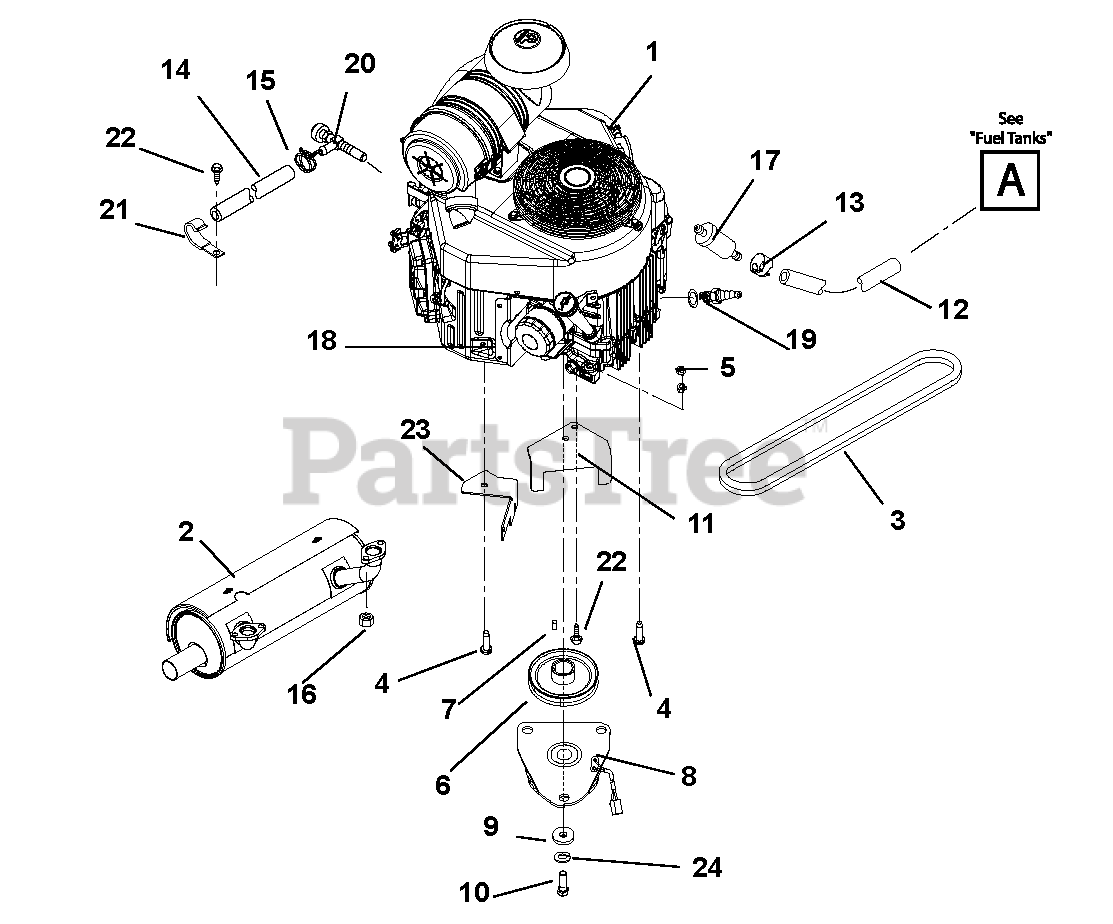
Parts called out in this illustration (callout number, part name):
1	Engine, Kawasaki FX 481
2	Muffler, Kawasaki
3	V-Belt, 53.7"
4	Bolt, Hex .38-16 x 1.25 FTH Grade 5 EP80
5	Nut, Locking Nylon Flange .31-18
6	Pulley, 4.50 OD x 1.127 Engine
7	Key, Square .25 x .625 x .25 SAE 8630 or SAE 1035
8	Clutch, Ogura
9	Washer, Flat Steel .463 x 1.375 x .250
10	Bolt, Hex .44-20 x 1.50 Grade 5 EP80
11	Anchor, Ogura Clutch
12	Hose, Gas Line .25" I.D.
13	Hose, Clamp
14	Hose, .50 x 6.00
15	Clamp, .88 Diameter Hose
16	Nut, Top Lock M8-1.25
17	Fuel Filter, Kawasaki
18	Oil Filter, Kawasaki
19	Spark Plug, Kawasaki
20	Drain, .50 Oil
22	Screw, Tapping .38-16 x .75 Hex Washer Head
23	Guard, Clutch Wire
24	Washer, Locking .44
